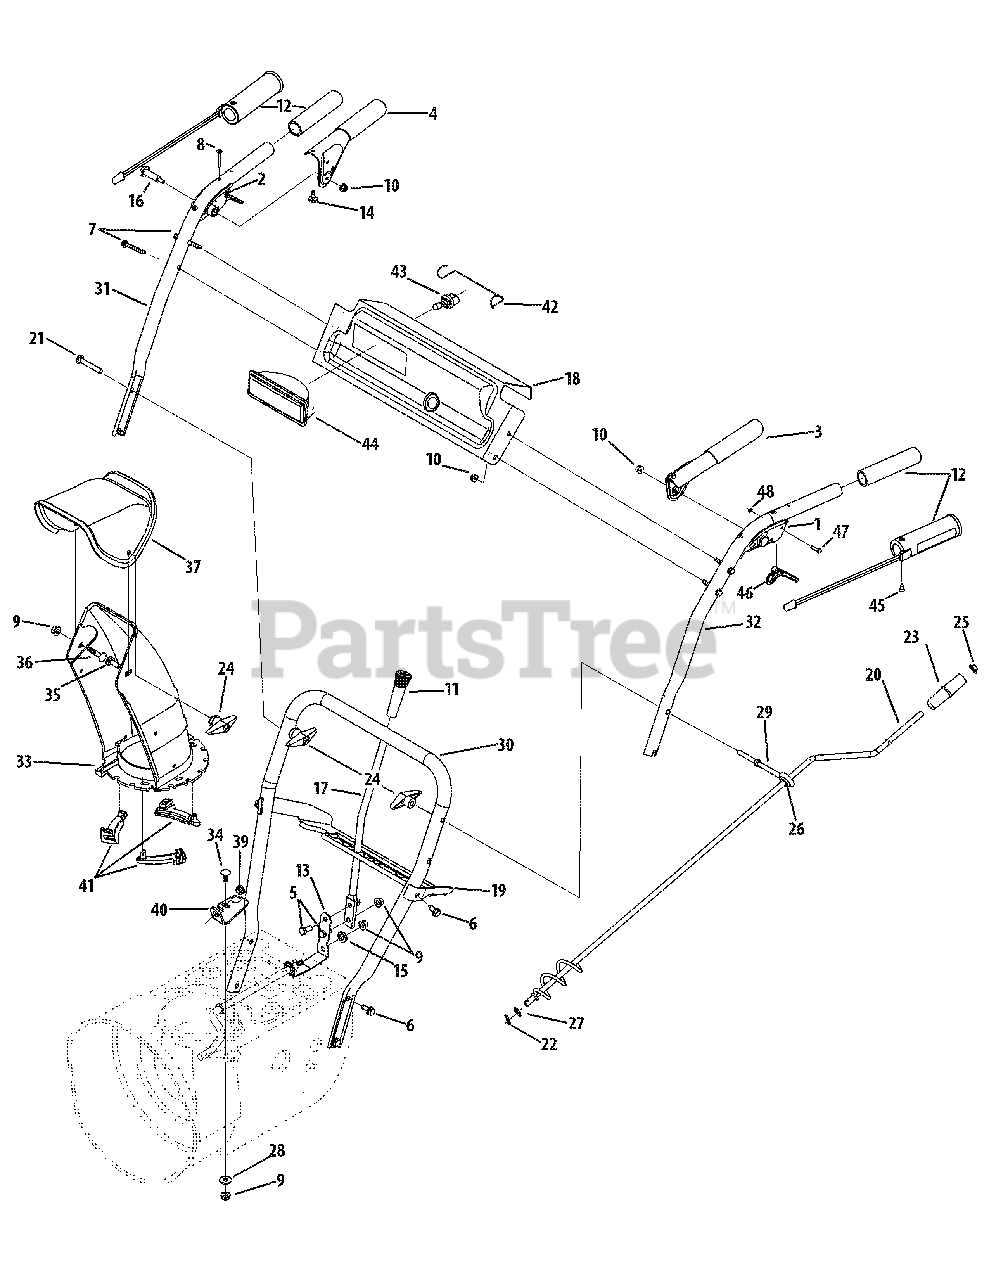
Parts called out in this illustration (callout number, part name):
1	Handle Assembly, Lock LH
2	Handle Assembly, Lock RH
3	Handle Assembly, Engagement LH
4	Handle Assembly, Engagement RH
5	Self-tapping Screws, 5/16-18 x .625
6	Self-tapping Screws, 5/16-18 x .750
7	Self-tapping Screws, 1/4-20 x 1.50
8	Machine Screw, #10/24 x 1.50
9	Flange Lock Nut, 5/16-18, Nylon
10	Flange Lock Nut, 1/4-20 x 1.50
11	Grip, 0.5 ID x 3.45
12	Grip, 1.0 ID x 5.0
12	Heated Grip
13	Shift Spring Lever
14	Rubber Bumper, .62 OD x .22
15	Flat Washer, .469 x .875 x .105
16	Shoulder Screw, 1/4-20, .437
21	Carriage Screw, 5/16-18, 2.25
22	Cotter Pin, .072 x 1.13
23	Crank Knob, 1.0 x 3.2
24	Wing Knob
25	Push Cap, 3/8 Rod
26	Grommet, .44 ID x .94 OD x .50
27	Flat Washer, .375 x .738 x .063
28	Flat Washer, .349 x .879 x .063
29	Chute Crank Eye Bolt
33	Lower Chute, 5.0 Dia
34	Carriage Bolt, 5/16-18, 1.0
35	Carriage Bolt, 5/16-18, 1.0
36	Carriage Bolt, 5/16-18, .750
37	Upper Chute
39	Plastic Bushing, .380
41	Chute Flange Keeper
42	Lens Retainer
43	Halogen Lamp, 12V, 27W
44	Lamp Lens Assembly
45	AB Screw
46	Steering Triggers
48	E-ring
